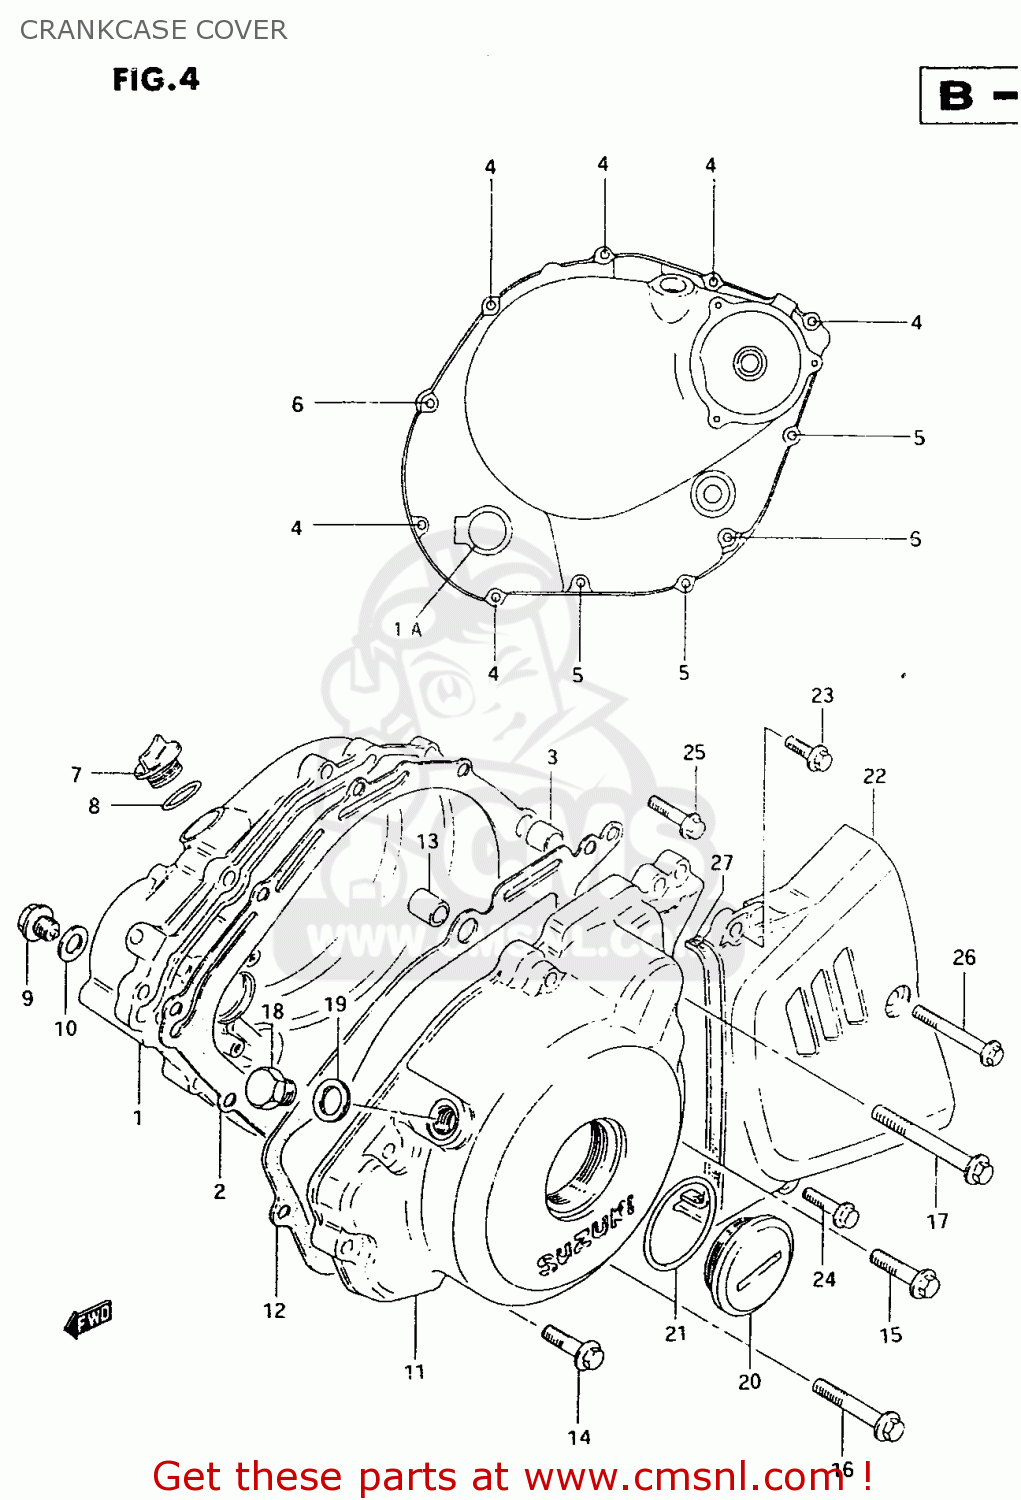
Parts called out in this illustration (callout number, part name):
1	COVER,CLUTCH
1A	LENS,OIL LEVEL CHECK
2	GASKET,CLUTCH COVER (NAS)
3	PIN
4	BOLT
5	BOLT
6	BOLT
7	PLUG(20X10)
8	O RING(D:3.1,ID:16.8)
9	PLUG(14X12)
10	GASKET(13.8X18.8X4.8) (NAS)
11	COVER,MAGNETO
12	GASKET,MAGNETO COVER (NAS)
13	PIN
14	BOLT
15	BOLT
16	BOLT
17	BOLT
18	PLUG,12X9
19	GASKET(12.1X16.2X3.7) (NAS)
20	PLUG,36X10
21	O RING(D:3.1,ID:32.7)
22	COVER,ENGINE SPROCKET
23	BOLT
24	BOLT
25	BOLT
26	BOLT
27	DAMPER,ENGINE SPROCKET COVER
